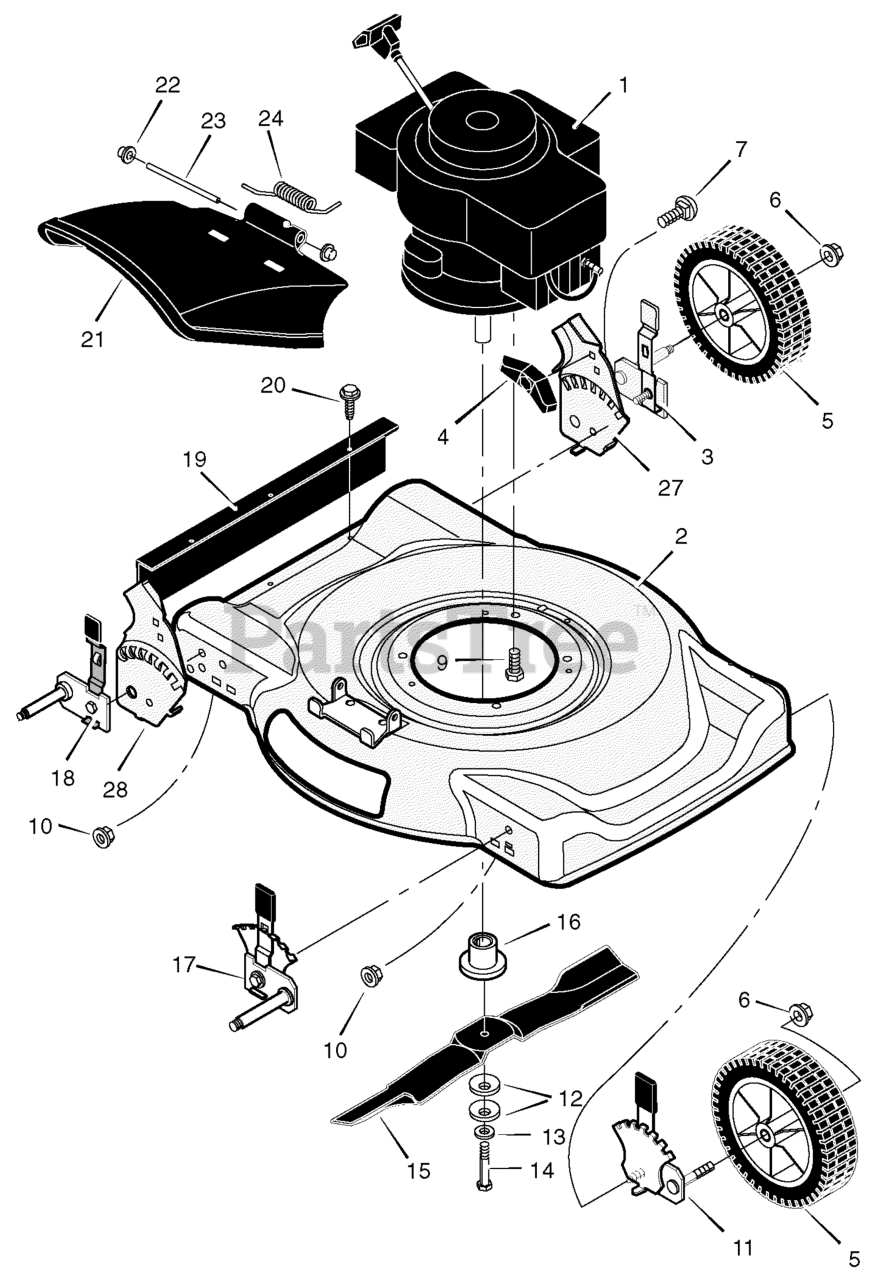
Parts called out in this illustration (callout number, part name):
1	Engine *
2	Housing
3	Height Adjuster, Left Rear (7" Wheels)
5	Wheel and Tire
6	Locknut, Flange
7	Bolt, Carriage
9	Bolt, Engine
10	Nut
11	Height Adjuster, Left Front (7" Wheels)
12	Washer, Belleville
13	Washer
14	Bolt, Hex
15	Blade, Side Discharge
16	Adapter, Blade
17	Height Adjuster, Right Front (7" Wheels)
18	Height Adjuster, Right Rear (7" Wheels)
19	Guard, Rear
21	Deflector, Chute
22	Push-On Cap
23	Pin, Pivot
24	Spring
27	Bracket, Left Handle
28	Bracket, Right Handle
